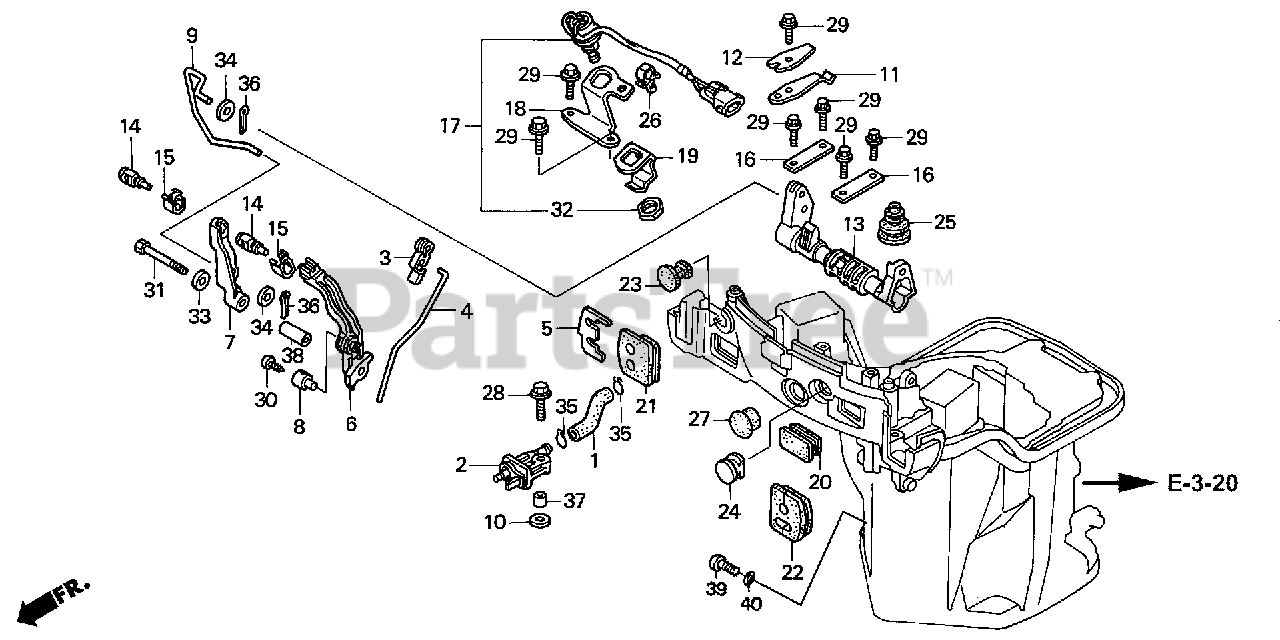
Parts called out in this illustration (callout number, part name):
1	TUBE A, FUEL
2	CONNECTOR ASSY., FUEL (B)
3	LINKAGE, PIVOT
4	ROD, THROTTLE
5	PLATE, REMOTE CONTROL CABLE
6	ARM, THROTTLE REMOTE
7	ARM, SHIFT LINK
8	HOLDER, THROTTLE ROD
9	ROD, SHIFT LINK
10	WASHER, PIVOT
11	SPRING, CLICK
12	SPRING, CLICK ASSIST
13	SHAFT, SHIFT
14	PIVOT, SHIFT
15	PLATE, LOCK
16	PLATE, SHIFT SHAFT
17	SWITCH ASSY., NEUTRAL
18	BRACKET, NEUTRAL SWITCH
19	PLATE, NEUTRAL SWITCH
20	GROMMET G, OIL CASE
21	GROMMET A, OIL CASE
22	GROMMET B, OIL CASE
23	GROMMET F, OIL CASE
24	GROMMET D, OIL CASE
25	GROMMET E, OIL CASE
26	CLIP A, BRAKE PIPE
27	CAP, HANDLE (LOWER)
28	BOLT, FLANGE (6X22) (CT200)
29	BOLT, FLANGE (5X12) (CT200)
30	BOLT, RECESSED (5X8)
31	BOLT, HEX. (6X40)
32	NUT, HEX. (20MM)
33	WASHER (6MM)
34	WASHER, PLAIN (7MM)
35	CLIP, TUBE (B12)
36	PIN, SPLIT (2.0)
37	COLLAR, DISTANCE (6MM)
38	COLLAR, DISTANCE (6X11X27)
39	BOLT, OIL CHECK
40	O-RING (5.5X1.5)
